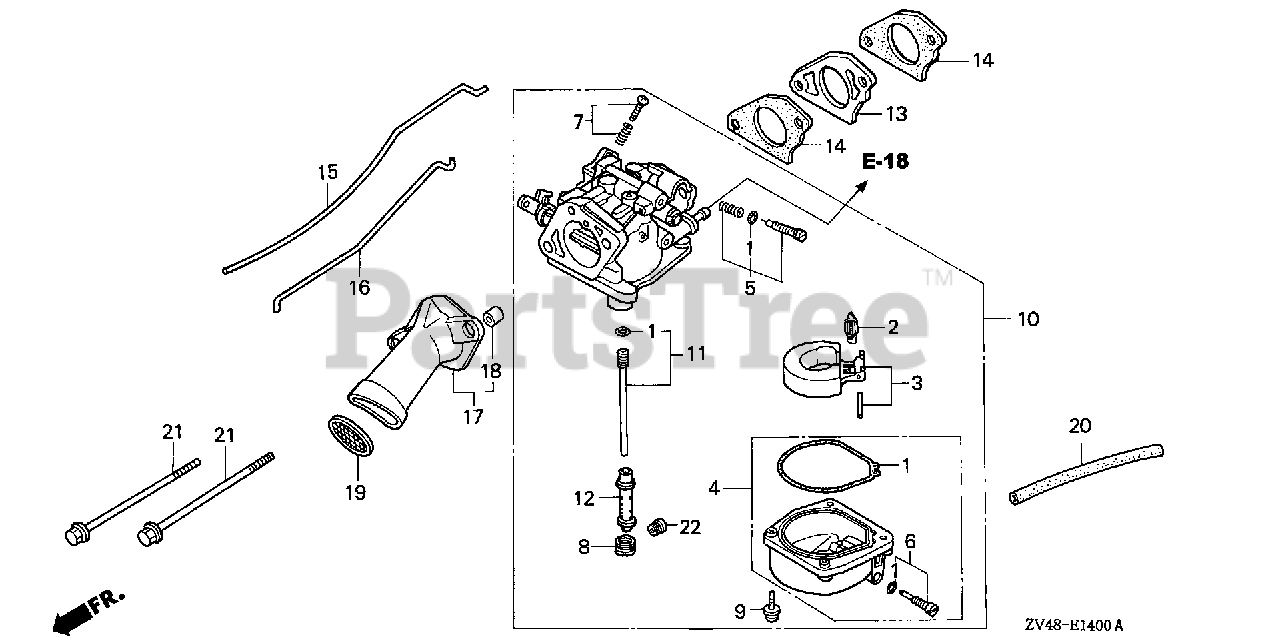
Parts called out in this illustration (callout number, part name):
1	GASKET SET
2	VALVE SET, FLOAT
4	CHAMBER SET, FLOAT
6	SCREW SET, DRAIN
8	SCREW, PLUG
9	SCREW-WASHER
10	CARBURETOR ASSY. (BG03F A)
11	JET SET (#48)
12	NOZZLE, MAIN
13	INSULATOR, CARBURETOR
14	GASKET, CARBURETOR
15	ROD, THROTTLE
16	ROD, CHOKE
17	GUIDE, AIR
18	COLLAR, DISTANCE
19	TRAP, FLAME
20	BULK HOSE, VINYL (3.5X6.5X8000) (3.5X6.5X100)
21	BOLT, FLANGE (6X95)
22	JET, MAIN (#98)
22	JET, MAIN (#100)
22	JET, MAIN (#102)
